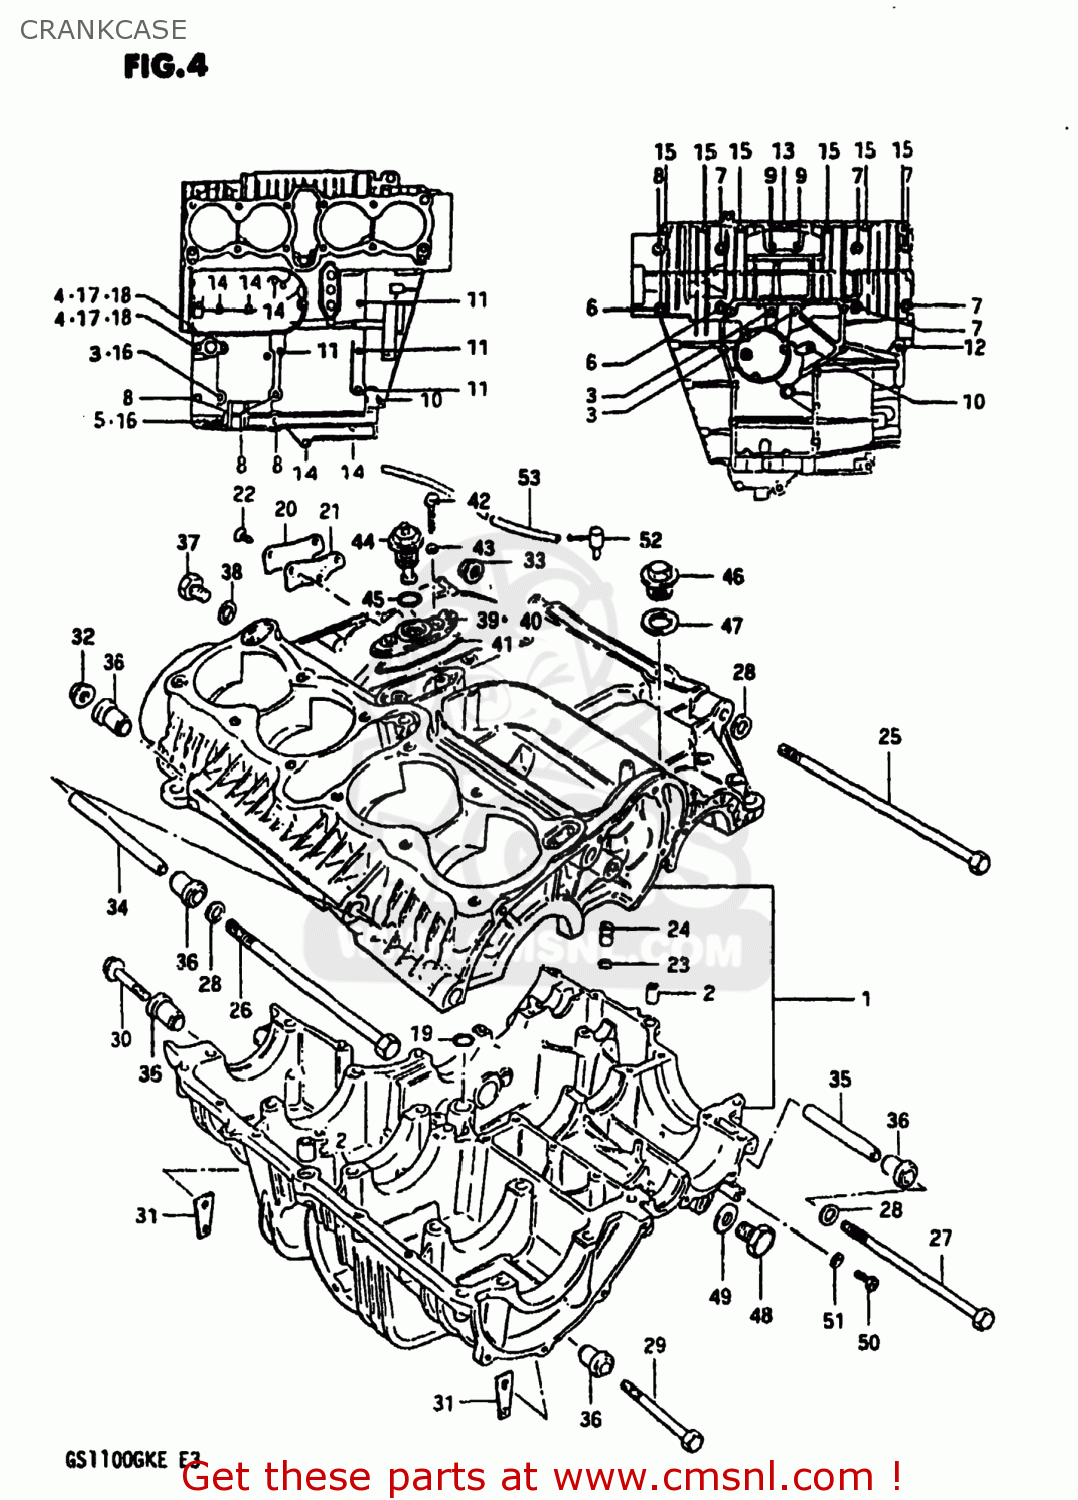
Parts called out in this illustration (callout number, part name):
1	CRANKCASE ASSEMBLY
2	PIN
3	BOLT
4	BOLT 8X110
5	BOLT
6	BOLT
7	BOLT (8X90)
8	BOLT (8X65)
9	BOLT 8X60
10	BOLT (6X90)
11	BOLT (6X75)
12	BOLT 6X55
13	BOLT 6X50
14	BOLT (6X45)
15	BOLT
16	NUT 8MM
17	NUT
18	GASKET 8.2X14X1 (NAS)
19	O RING(D:3.2,ID:12.9)
20	CAP,OIL GALLERY
21	GASKET,OIL GALLERY (MCA)
22	SCREW
23	O RING(D:1.05,ID:3.1)
24	UNION
25	BOLT
26	BOLT
27	BOLT
28	WASHER
29	BOLT
30	BOLT 10X55
31	NUT
32	NUT
33	NUT 10MM
34	SPACER
35	SPACER
36	BUSH
37	PLUG (14X12)
38	GASKET(14X19.2X2) (NAS)
39	HOUSING,OIL PRESSURE SWITCH
40	HOUSING,OIL PRESSURE SWITCH
41	O RING,PRESSURE SWITCH HOUSING
42	BOLT
43	WASHER
44	SWITCH ASSEMBLY
45	O RING(D:1.9,ID:18.8)
46	PLUG
47	GASKET
48	PLUG
49	GASKET(14X19.2X2) (NAS)
50	SCREW(6X10)
51	WASHER
52	BPLUG,BEVEL GEAR BREATHER
53	HOSE
